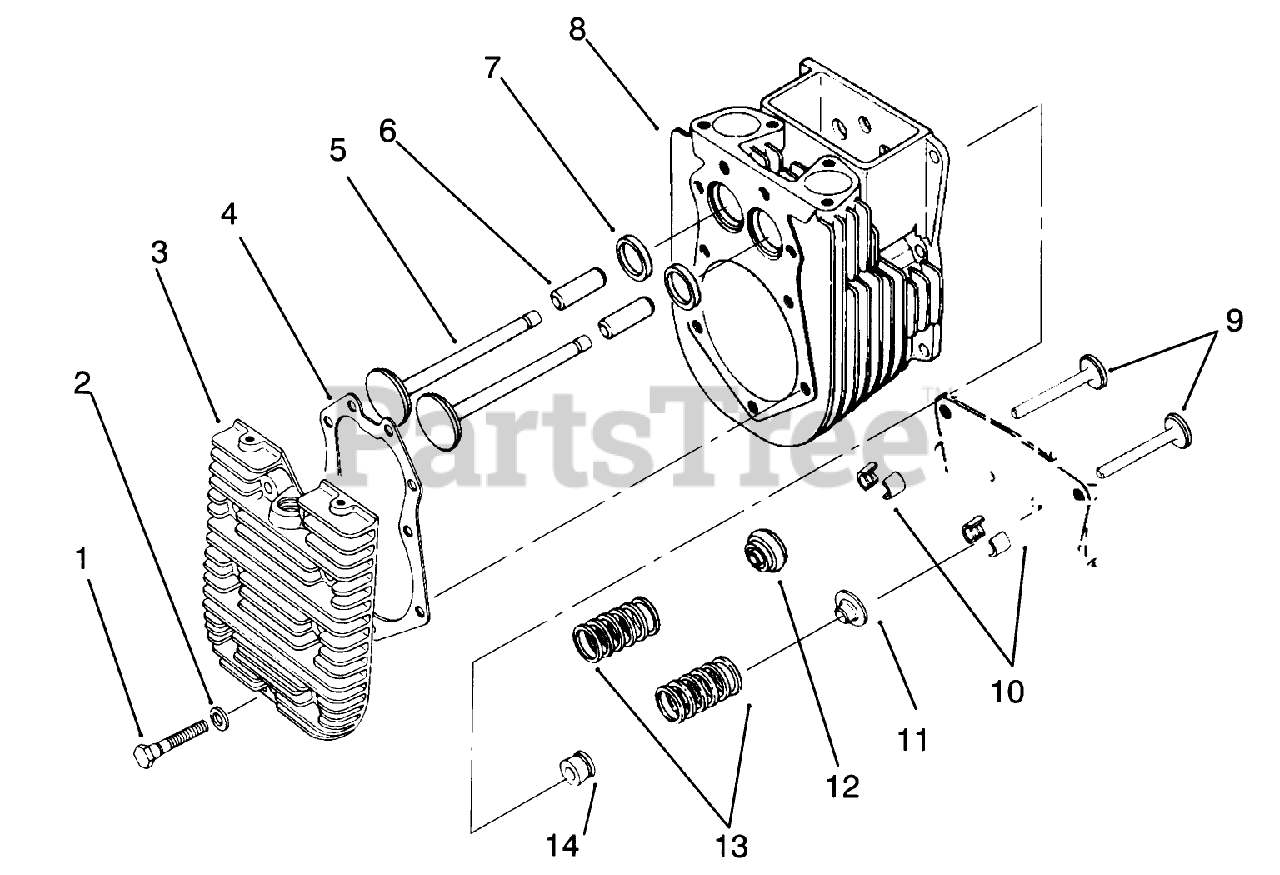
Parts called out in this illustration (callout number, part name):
1	Screw H.C.
2	Washer
3	Head-Cylinder
4	Gasket-Head
5	Valve-Exhaust
6	Guide-Valve
7	Inset-Valve Seat
8	Kit-#2 Cylinder Barrel (Incl. Ref. #2-4)
10	Kit-Retainer
11	Retainer-Spring
12	Rotator
13	Spring-Valve
14	Seal-Valve Stem
